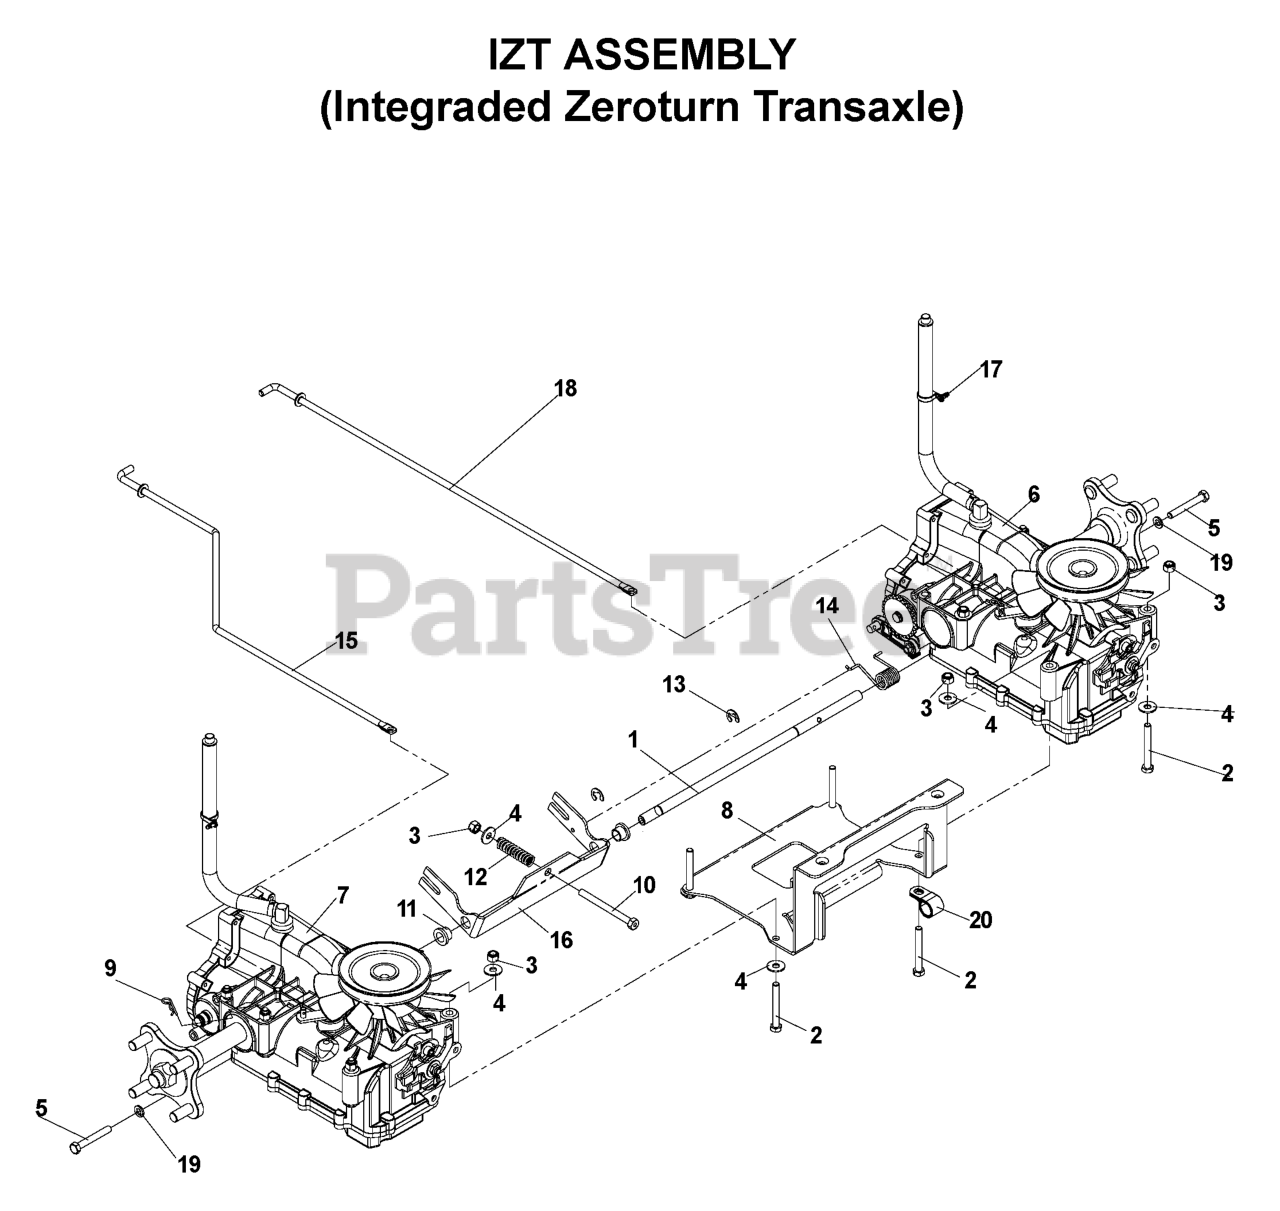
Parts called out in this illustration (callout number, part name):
2	BOLT 5/16C X 2 1/2
3	NUT 5/16 NYLOC
4	WASHER 5/16 FLAT
5	HEX SCREW-.313C X 2.25 GR8
6	HG_IZT-LEFT
7	HG_IZT-RIGHT
8	IZT SUPPORT
9	HAIRPIN #2
10	BRAKE BOLT
11	BUSHING, FLANGED NYLON
13	E-RING 1/2 (2 2)
14	TORSION SPRING
15	IZT BYPASS LINKAGE
16	BRAKE U-ARM
18	BYPASS LINKAGE-LH
19	WASHER.LOCK.HVY.HLCL.SPR.5/16
